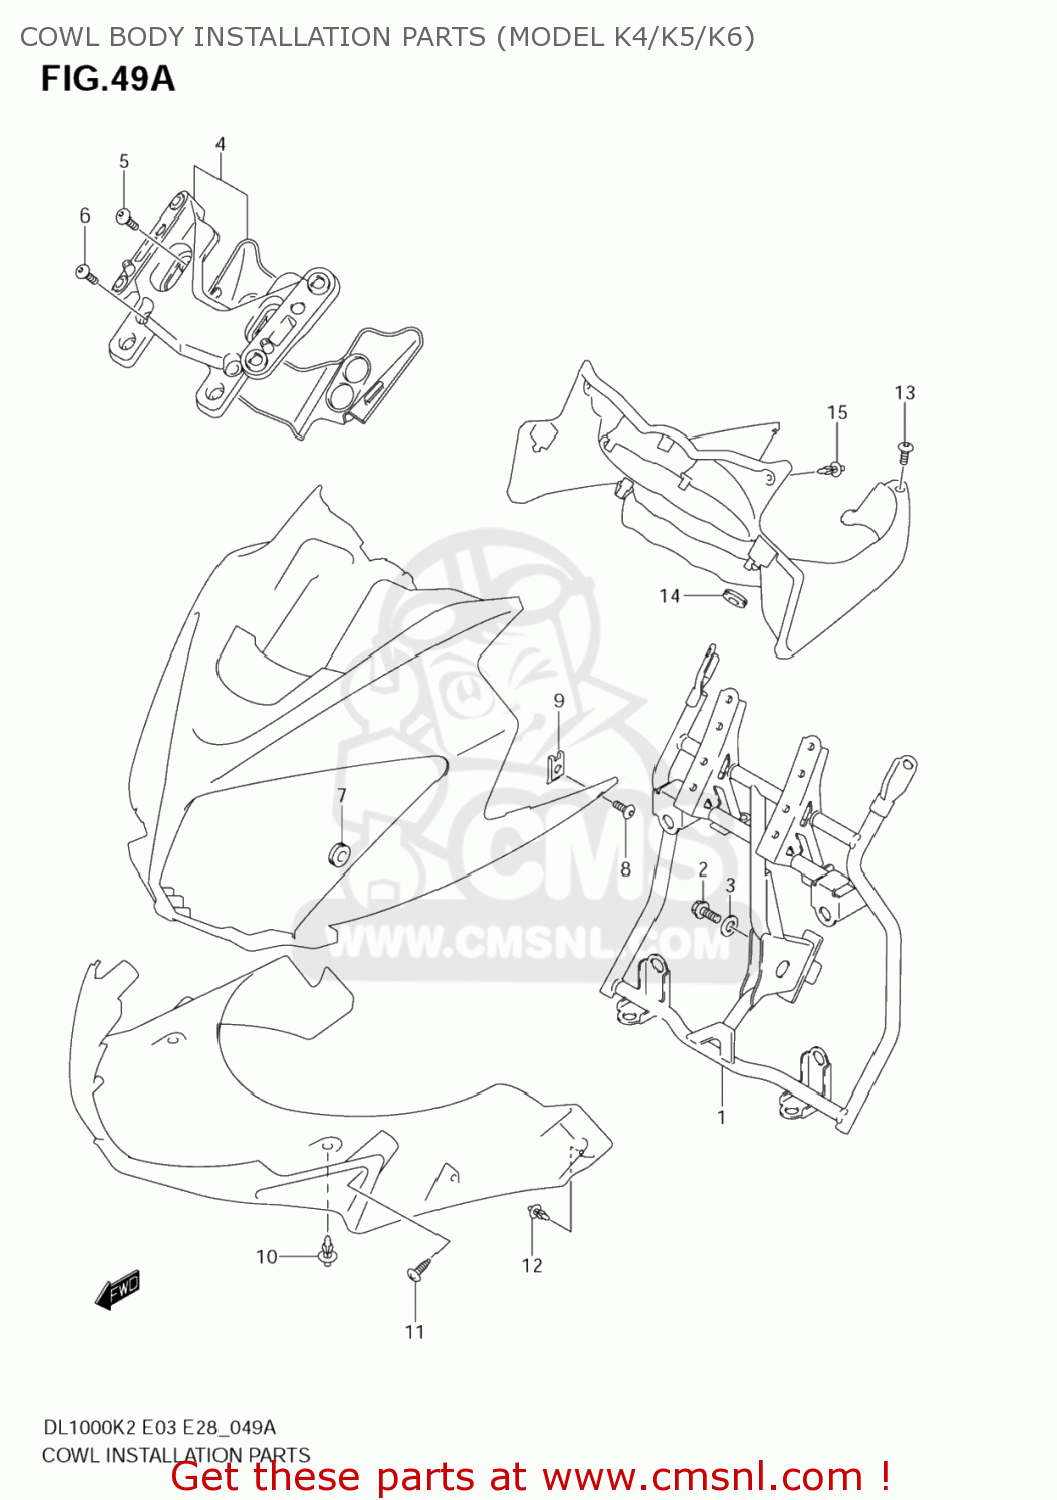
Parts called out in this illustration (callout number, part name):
1	BRACE COMP,COW
2	BOLT(8X20)
3	WASHER
4	BRACE ASSY,WINDSCREEN
5	SCREW(6X20)
6	SCREW(6X16)
7	CUSHION
8	SCREW(5X13)
9	NUT
10	CLIP
11	SCREW
12	CLIP(BLACK)
13	SCREW(6X10)
14	CUSHION
15	CLIP(BLACK)
